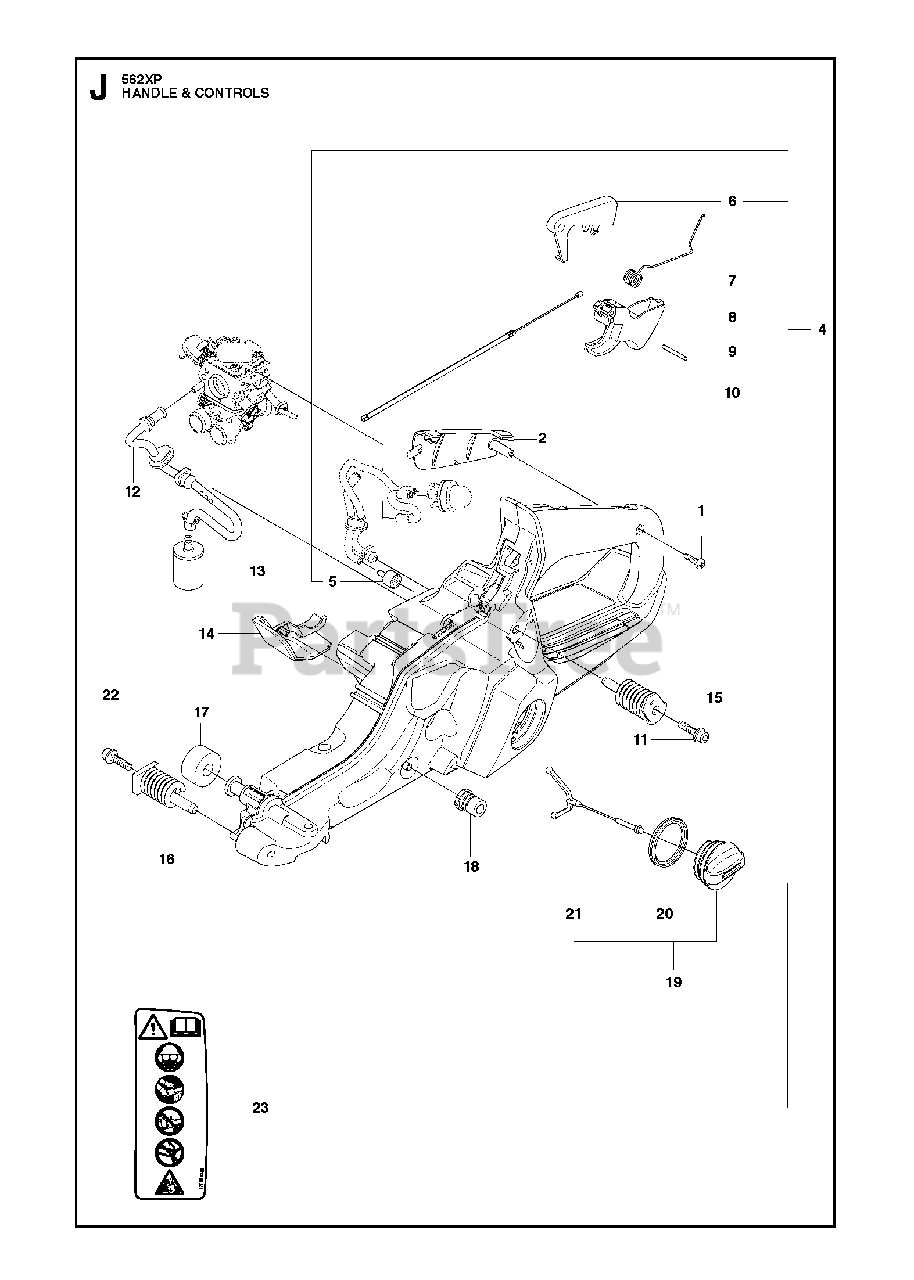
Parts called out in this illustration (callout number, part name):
2	HANDLE INSERT
4	RP FUEL TANK ASSY
5	FUEL TANK VENT
6	THROTTLE LOCKOUT
7	SPRING
8	THROTTLE
9	PIN
10	THROTTLE CABLE ASSY
12	RP FUEL HOSE
13	FUEL FILTER
15	RP ANTIVIBRATION ELEMENT
16	ANITVIBRATION ELEMENT
17	DEFLECTION LIMITER
18	LATERAL SUPPORT
19	TANK CAP
20	SEALING
21	TANK LOCK
23	DECAL
